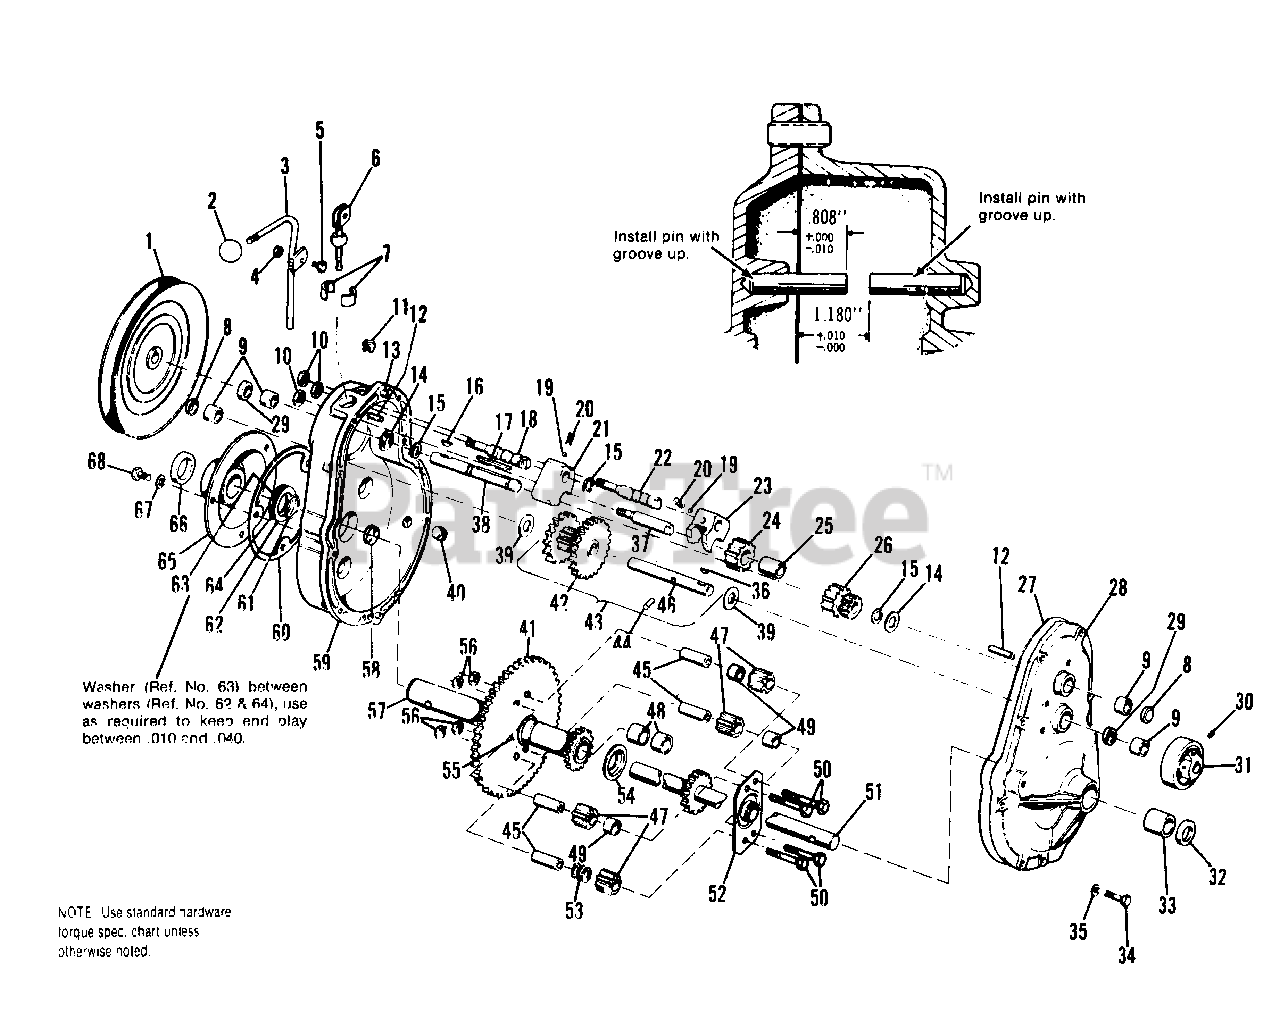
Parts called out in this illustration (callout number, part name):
1	PULLEY, Transmission
3	LEVER ASSY., Shift
4	LOCKNUT, Hex, 1/4-20
5	CAPSCREW, Hex Hd., 1/4-20 x 3/4
6	ROD ASSY., Shift
7	BUSHING, Half
10	NUT, Hex, Full, 7/16-14
12	PIN ASSY., Roll
13	PIN, Roll, 3/8 x 1
15	RING, Retaining
16	KEY, Hi-Pro
18	SHAFT, Ref.
21	FORK, Shift, Reverse
22	SHAFT, Hi-Lo
23	FORK, Shift, I & II
24	PINION, Reverse
25	BEARING, Roller
26	PINION ASSY., Hi-Lo
28	COVER ASSY., Gear Case (Includes Ref. Nos. 8, 9, 14 & 33)
30	SETSCREW, 5/16-18 x 5/16
31	DRUM, Brake
34	CAPSCREW, Hex Hd., 5/16-18 x 1-1/4
35	LOCKWASHER, 5/16
37	SHAFT, Pinion, Reverse
38	SHAFT, Pulley
40	PLUG, Pipe, 3/8
41	GEAR, Drive
42	GEAR ASSY., Cluster
43	SHAFT & GEAR ASSY.
44	PIN, Dowel
45	SPINDLE, Diff.
46	SHAFT, Brake
47	PINION, Diff.
49	SPACER, Diff.
50	CAPSCREW, Hex Hd., 3/8-16 x 2-1/2
51	AXLE ASSY., L.H.
52	PLATE ASSY., Diff.
54	CUP, Thrust
56	LOCKNUT, Hex, 3/8-16
57	AXLE ASSY., R.H., W/Bushing
58	PLUG, Expansion
59	CASE ASSY., Gear (Includes Ref. Nos. 6, 7, 8, 9, 13 & 14)
61	RING, Snap
65	PLATE ASSY., Support
66	SEAL, Oil
67	LOCKWASHER, 3/8
68	CAPSCREW, Hex Hd., 3/8-16 x 7/8
